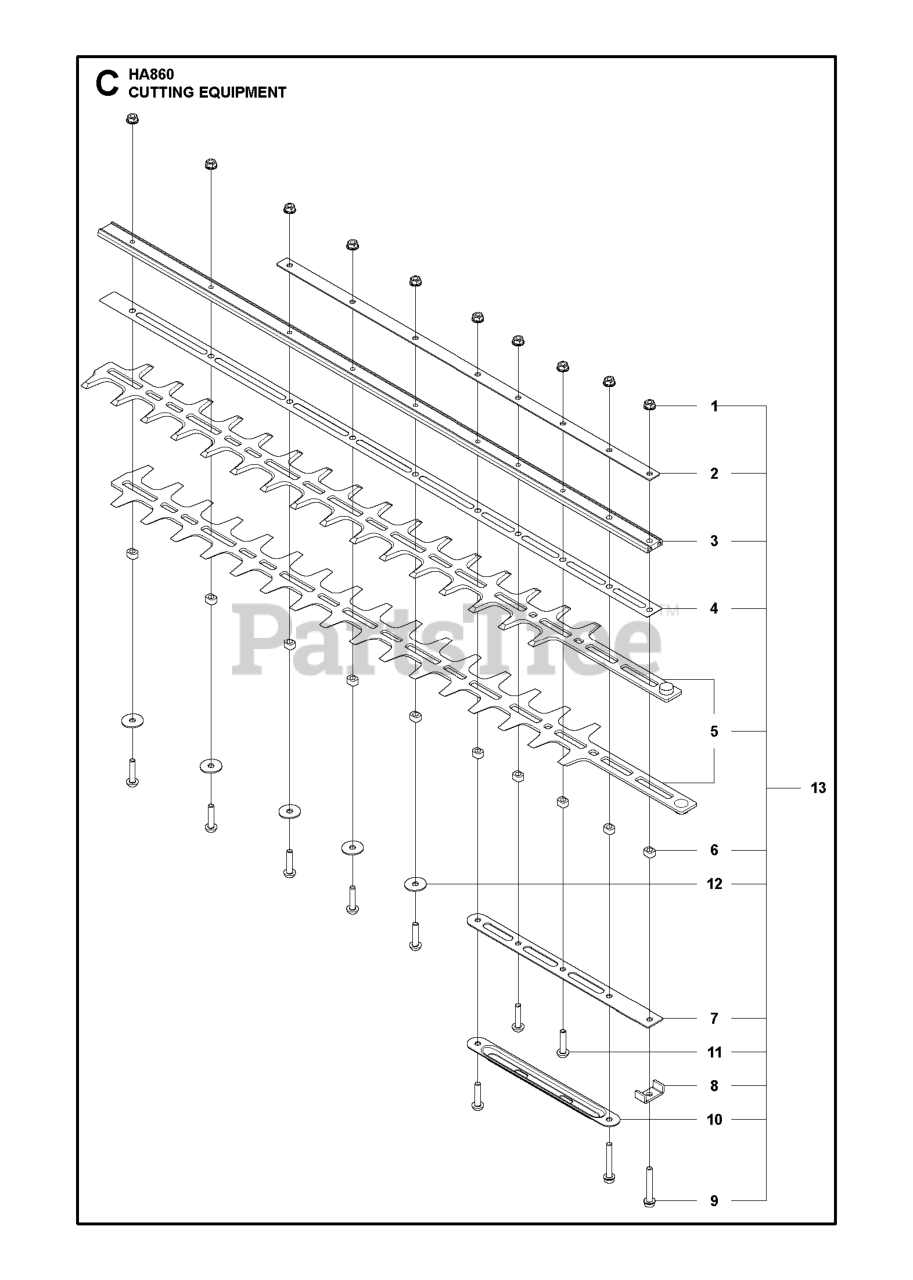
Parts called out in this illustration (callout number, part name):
1	NUT HEXAGON LOCK WITH FLANGE M
2	BAR PLATE UPPER
3	GUIDE BAR HD/HS60
4	WEAR PLATE
5	BLADE KIT HD60
6	SPACER CUTTING DECK
7	BAR PLATE LOWER
10	BAR PLATE LOWER
11	SCREW HEXALOBULAR SOCKET BUTTO
12	WASHER PLAIN 5.5X19X1.2 ST TBO
13	CUTTING DECK KIT HD60
